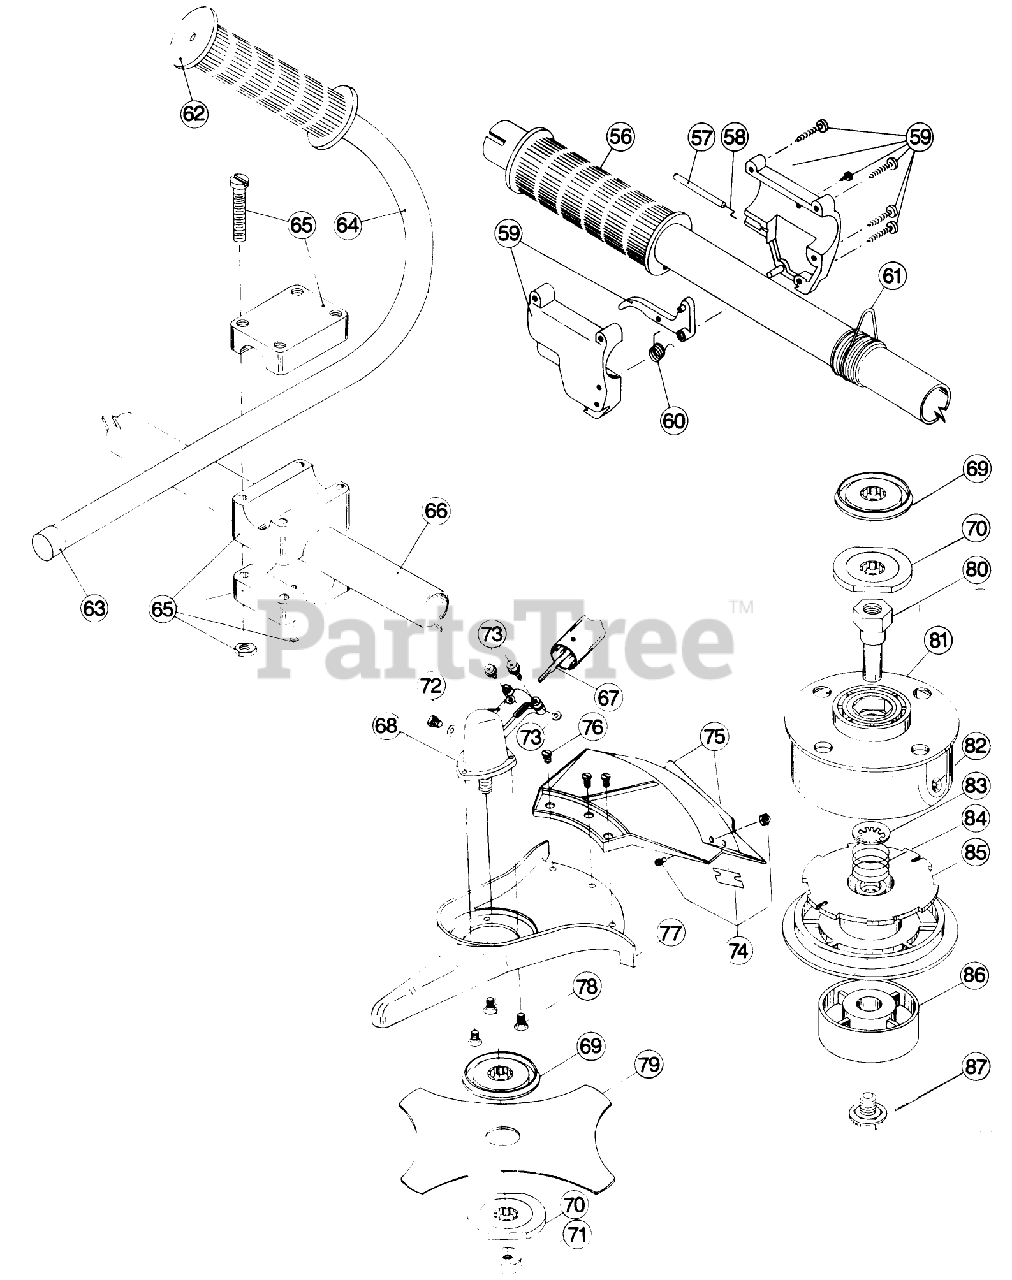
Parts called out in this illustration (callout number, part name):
58	THROTTLE CABLE WIRE
60	THROTTLE TRIGGER SPRING
63	TUBE CLOSURE
65	HANDLE BRACKET ASM
66	DRIVE SHAFT HSG ASM
68	GEAR BOX ASM
74	BLADE ASM
75	GUARD & BLADE ASM
76	GUARD MNTG SCREW ASM
77	GUARD MOUNTING SCREWS
81	OUTER SPOOL EYELET ASM
83	RETAINER
